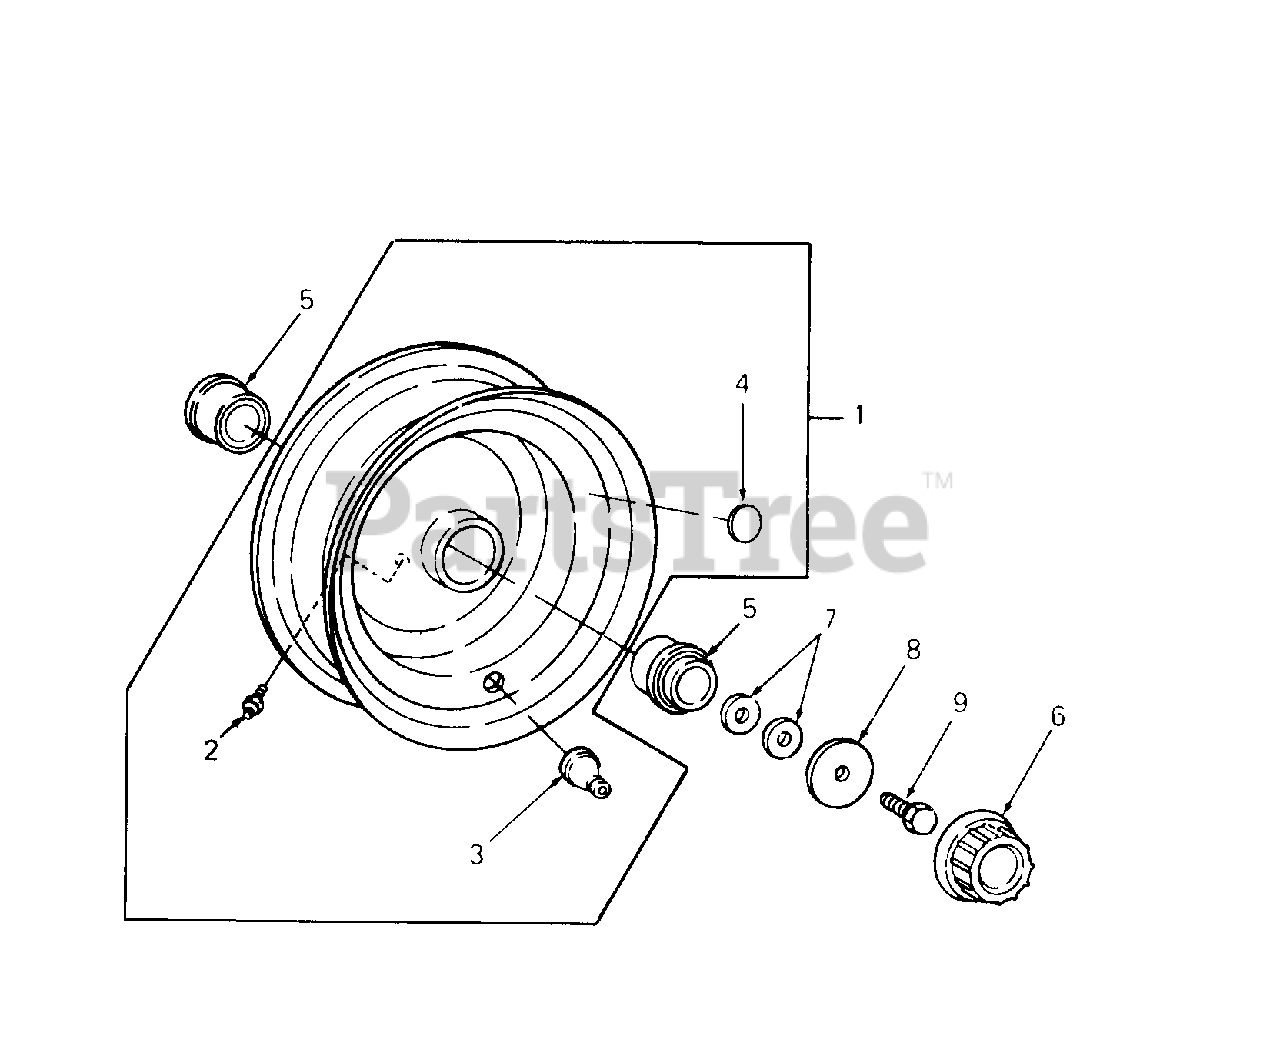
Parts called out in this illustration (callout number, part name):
1	Wheel Assy, Front
2	Fitting, Lube
3	Valve, Tubeless Air
4	Label, Inflation
5	Bearing, Wheel Ball
6	Cap, Hub
7	Washer, Flat, .531 X 1.25 X .100 Thk
8	Washer, Flat, .535 X 1.92 X .060 Thk
9	Bolt, Patch, 1/2-13 X 1.0 Lg GR5
